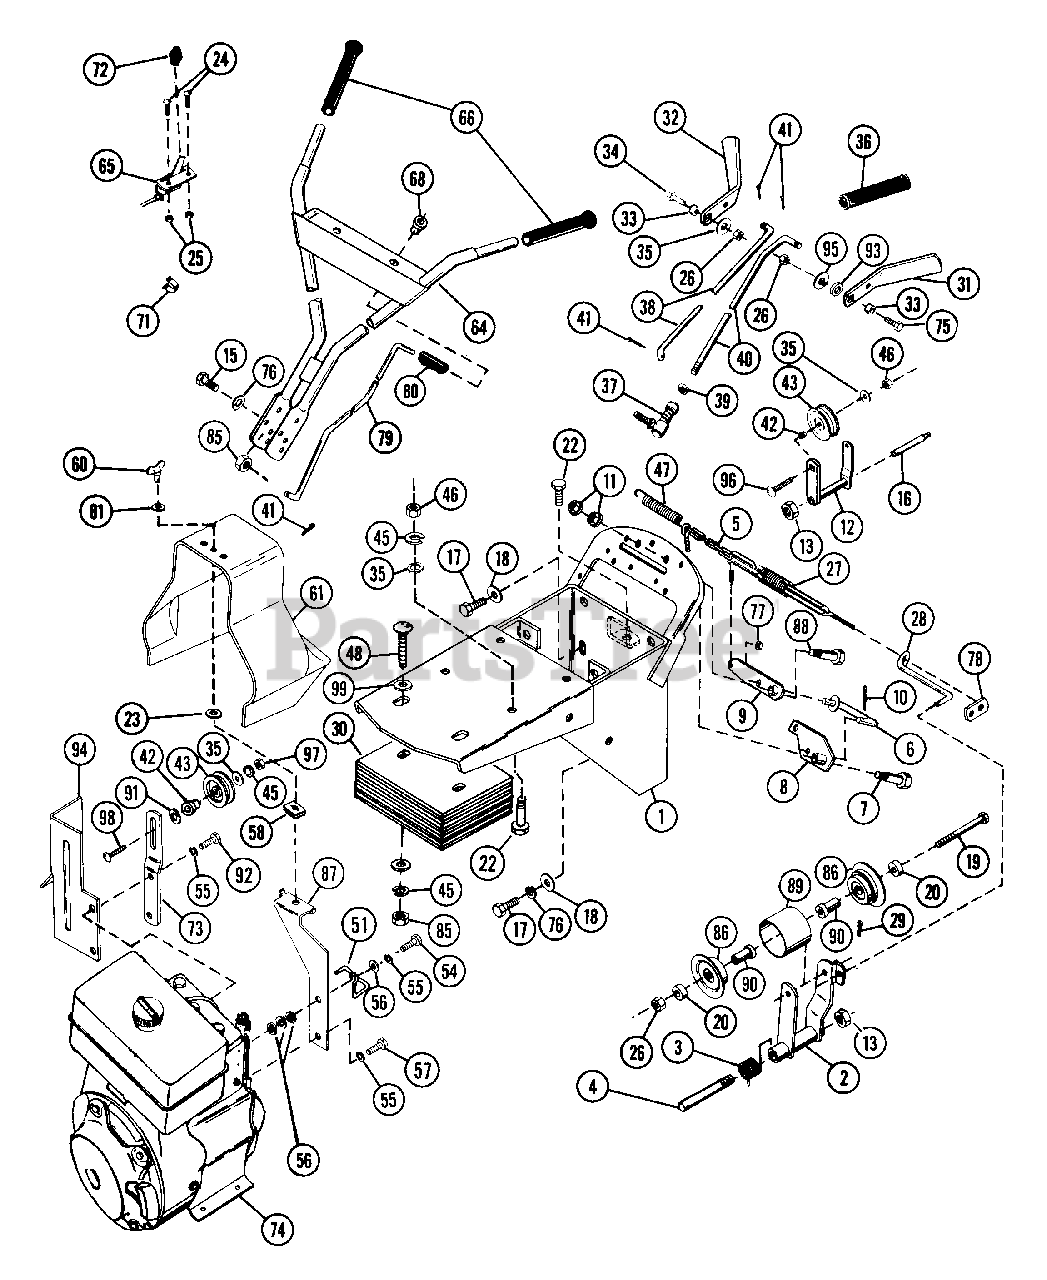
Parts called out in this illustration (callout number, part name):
2	IDLER ARM
3	SG-TORS .076X.89X1.98
4	IDLER PIN
5	CLUTCH CHAIN
6	CLUTCH LINK
7	SHOULDER BOLT
8	CLUTCH BELLCRANK
9	SPRING ARM
10	PIN COTTER 1/16" X 1/2"
11	NUT-LK-CTR .375-16 GR A PL
12	IDLER ARM
13	NUT-LK-FLG .375-16 PL
14	SHOULDER BOLT
15	BLT-HEX .38-16X1.00 PL
16	IDLER PIN
17	BLT-HEX .38-16X1.25 PL GR 2
18	WSHR-FL-STL.406X.812X.065PL
19	BLT-HEX .31-18X3.75 PL GR2
20	BSHG, SPCR.500X.750X.321 PM
22	BLT-HEX .31-18X1.00 PL GR 2
23	NUT-RETNR
24	SCR-MCH 10-24X.50 SLRH PL
25	NUT-KEPS 10-24 PL
26	NUT-LK .312-18 GR A PL
27	CLUTCH SPRING
28	CLUTCH LINK
29	PIN-HAIR INT .06X.18X.77
30	WEIGHT WAFER
31	DRIVE CLUTCH HANDLE
32	TILLER CLUTCH HANDLE
33	SPACER BUSHING .5 X .32 X .21
34	BLT-HEX .31-18X1.25 PL GR2
35	WSHR-FL-STL .38X.875X.083 PL
37	SNAP IN BALL JOINT
38	DRIVE CLUTCH ROD
39	NUT-LK-CTR .312-24 PL
40	TILLER CLUTCH ROD
41	PIN-COTR .09X.75 PL
42	BSHG, FLG .325X.499X.26X.88
43	IDLER
45	WSHR-LK .312X.097 PL HVY
46	NUT-LK .312-18 GR A PL
47	SG-TENS .039X.44X1.75 WLD 3.2
48	BLT-RDHDSQNK .38-16X3.25 PL
51	FORWARD BELT FINGER
54	BLT-HEX .31-24X1.00 PL GR5
55	WSHR-LK-INT .313X.030 PL
56	WSHR-FL-STL .323X.625X.062 PL
57	BLT-HEX .31-24X.50 GR5
58	NUT-SPEED 1/4 TURN SOUTHCO
60	SCR-WING .25 TURN SOUTHCO
61	BELT COVER
64	HANDLEBAR
65	THROTTLE CONTROL
66	HANDLEGRIP
68	SNAP BUSHING
71	CABLE RETAINER
72	KNOB, CONTROL-THROTTLE
73	REVERSE IDLER BRACKET
74	ENGINE
76	WSHR-LK .375X.115 HVY PL
77	NUT-LK 8-32 GR A PL
78	RETAINING NUT
79	CLUTCH ROD
80	GRIP
81	WSHR-FL-STL .250X.562X.049 PL
85	NUT-HEX .375-16
87	BELT COVER BRACKET
88	SHOULDER BOLT
90	BEARING SPACER
91	SPACER
92	BLT-HEX .31-24X.75 PL GR5
93	SPACER
94	HEAT SHIELD
95	WSHR-FL-STL .344X1.375X.075 PL
96	BLT-RDHDSQNK .31-18X1.38SHT PL
97	NUT-HEX .312-18
98	BLT-RDHDSQNK .31-18X1.75 SHTPL
99	WSHR-FL-STL .630X1.005X.062 PL
100	BLT-HEX .31-18X.75 PL GR2
